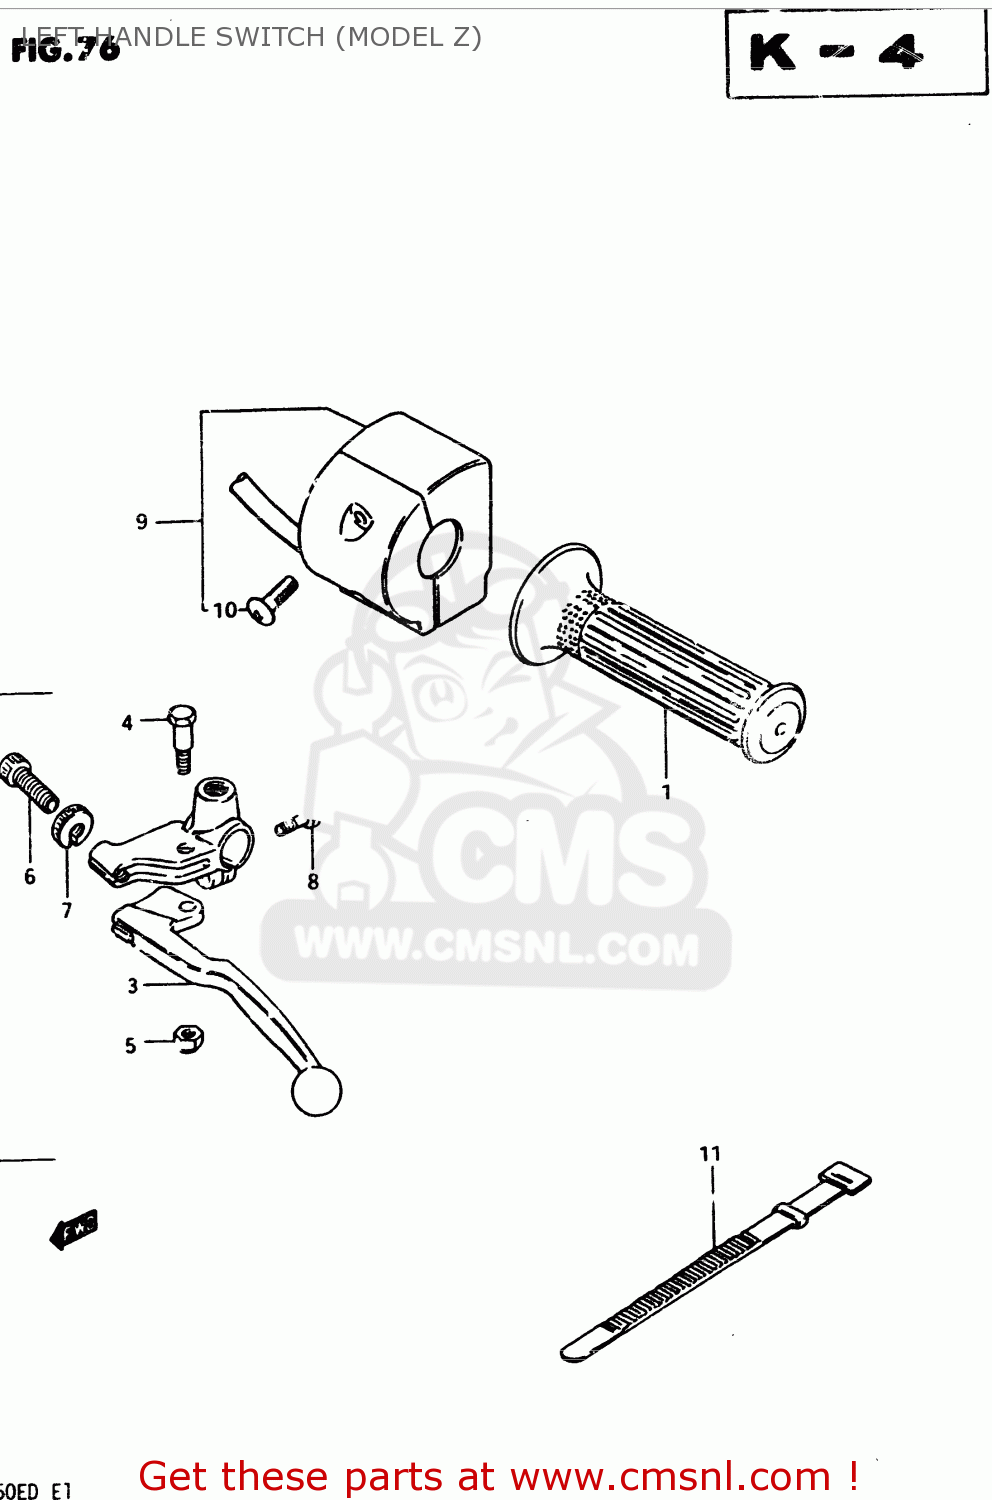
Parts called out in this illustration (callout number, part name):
1	GRIP,LEFT
2	LEVER ASSY, CLUTCH
3	LEVER,CLUTCH
4	BOLT,LEVER
5	NUT 6MM
6	ADJUSTER,CABLE
7	NUT,CABLE ADJUSTER LOCK
8	BOLT
9	SWITCH ASSY, HANDLE LH
10	SCREW
11	CLAMP(L:120)
